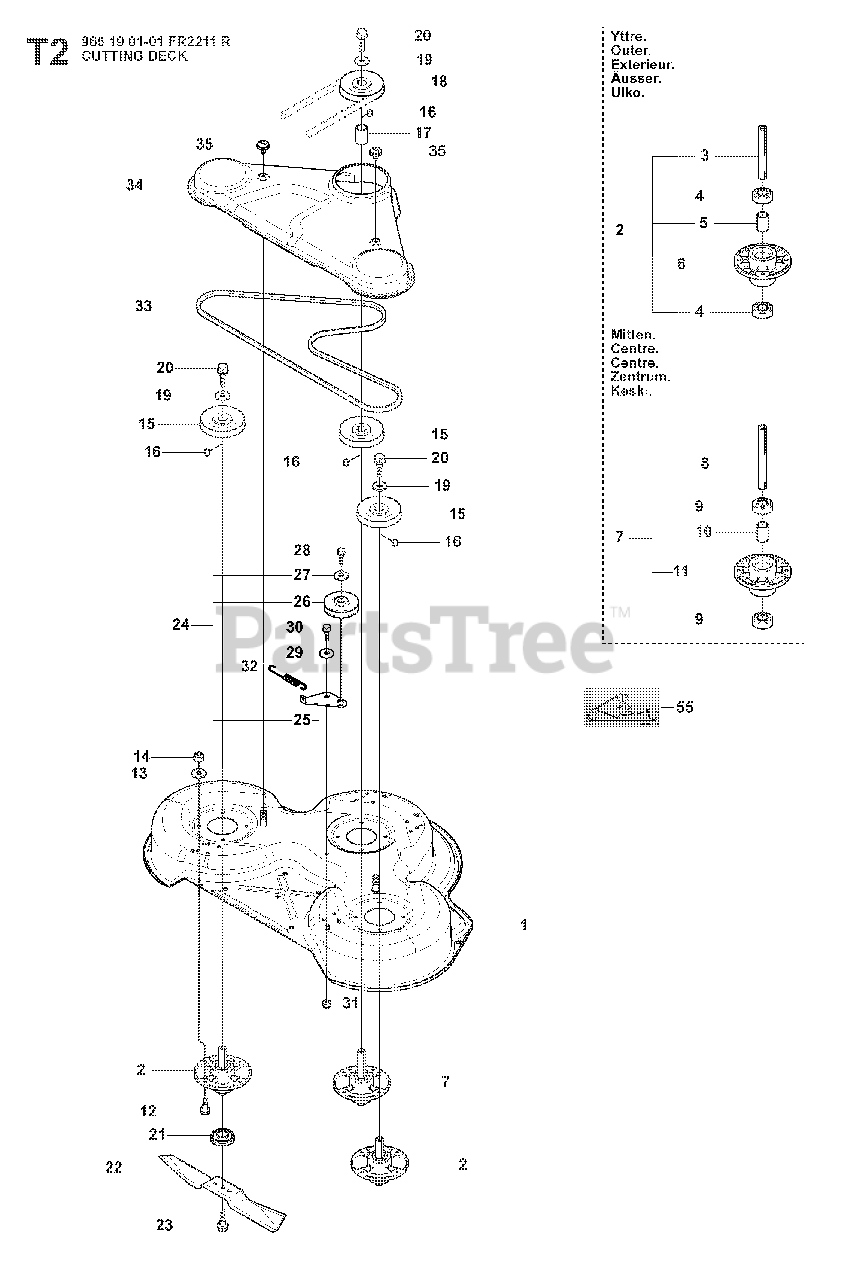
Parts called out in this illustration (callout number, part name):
2	RP SPINDLE ASSY
6	BEARING HOUSING
11	BEARING HOUSING
13	WASHER BRB 8.4X17
14	LOCKNUT M8
26	PULLEY
29	WASHER
31	LOCKNUT M8
